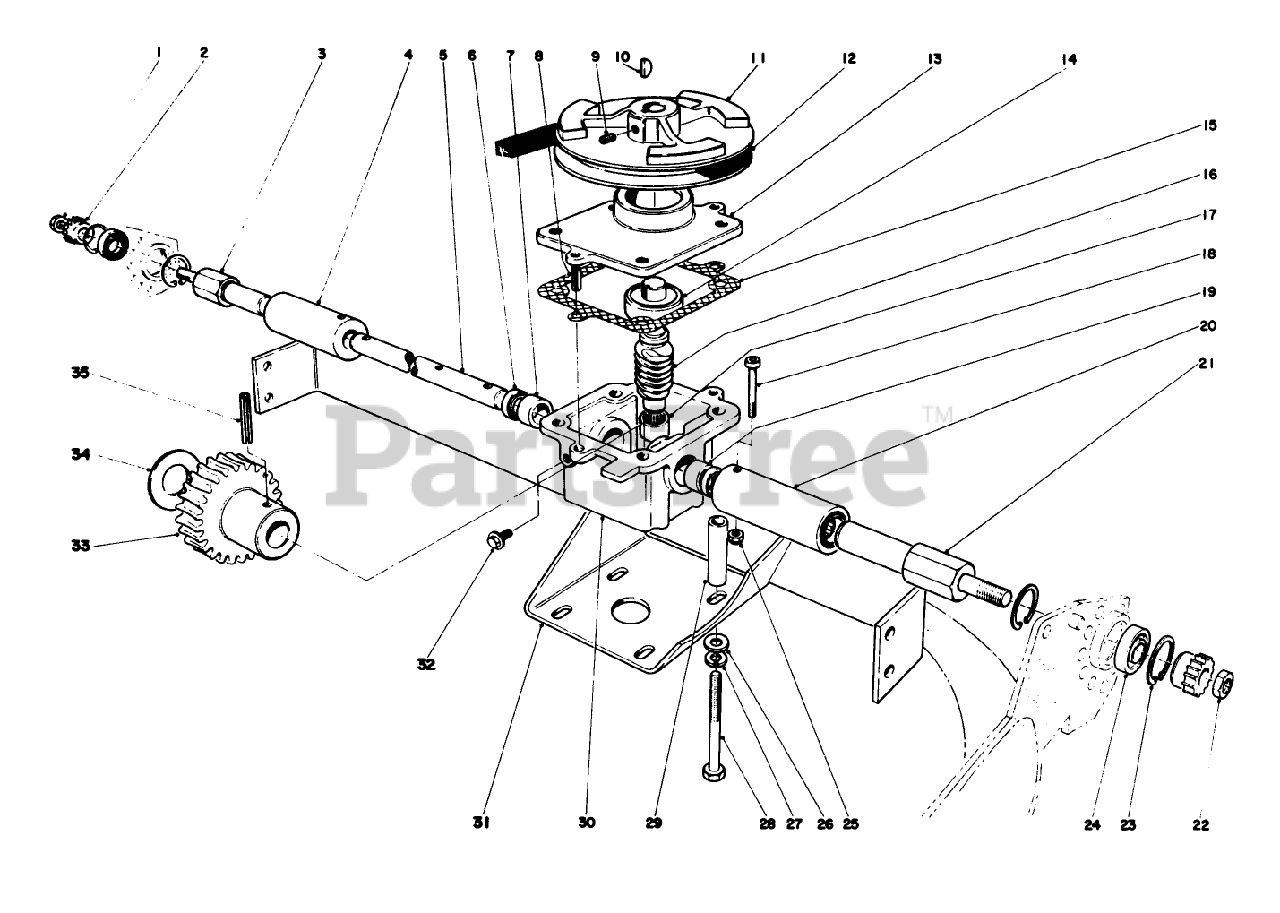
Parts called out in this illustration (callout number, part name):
1	NUT-HJ
2	Pinion Kit
3	OUTPUT SHAFT
4	Clutch Assembly, Right
5	GEAR BOX SHAFT
6	Seal
7	Bushing
8	3/16 X 1/2 ROLL PIN
9	SCREW-HSH
10	3/32X5/8 WOODRUFF KEY
11	GEAR BOX PULLEY
12	V BELT
13	Cover Gear Box
14	Bearing
15	GASKET
16	WORM SHAFT
17	.437 NEEDLE BEARING
18	DRIVE SCREW
19	Bushing
20	Clutch Assembly, Left
21	OUTPUT SHAFT
22	NUT-JAM, LH
23	1-1/8X056 IN SNP RING
24	.375 RPP BALL BEARING
25	NUT-LOCK, NI
26	WASHER-FLAT
27	WASHER-LOCK
28	SCREW-HH
29	GEAR CASE SPACER
30	Gear Case (Incl. Ref. #6-7 & 17 & 19)
31	Support-Gear Case
32	NYLON SCREW
33	WORM GEAR
34	THRUST WASHER
35	5/32 X 7/8 ROLL PIN
